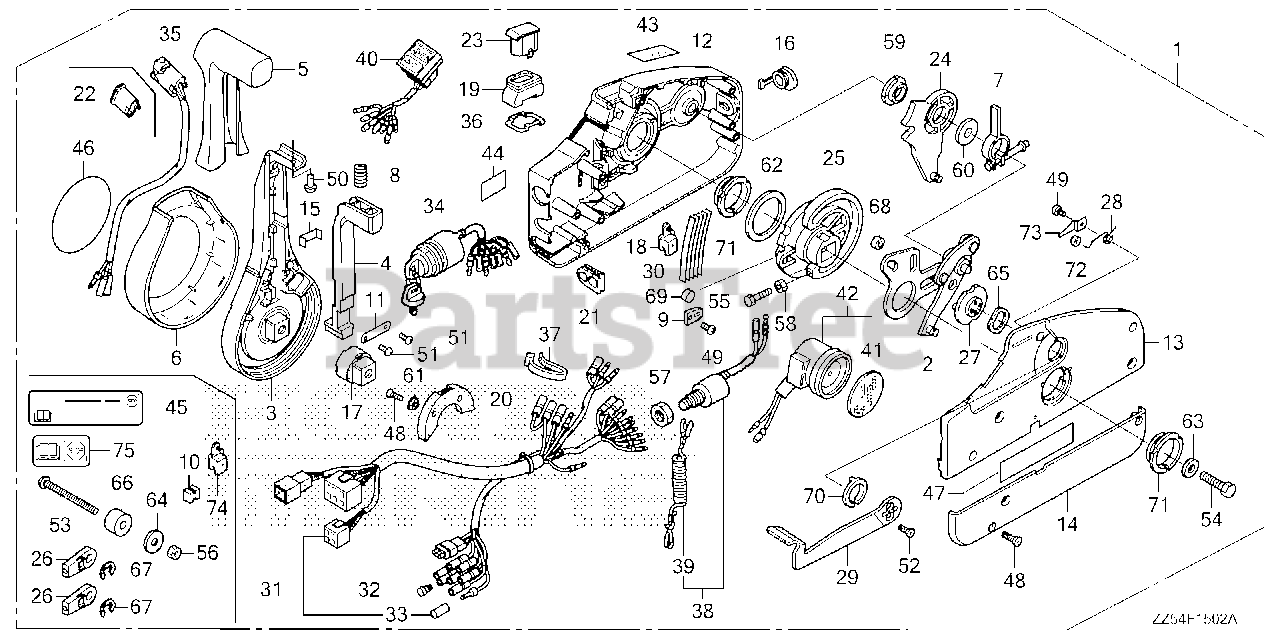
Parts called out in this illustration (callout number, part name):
1	BOX ASSY., REMOTE CONTROL (NHK MEC)
2	PLATE ASSY.
3	LEVER, HAND
4	ARM, NEUTRAL LOCK
5	GRIP
6	COVER, LEVER
7	ARM ASSY., BRAKE
8	SPRING (2)
9	CLIP, DETENT
10	SPACER (1) (LOOSE PARTS)
11	BRACKET
12	HOUSING, FR.
13	HOUSING, RR.
14	PANEL, BACK
16	CAP, RUBBER
17	ADJUSTER
19	SEAL, RUBBER
20	HOLDER, NEUTRAL LOCK
21	GROMMET, WIRE (14)
22	COVER, GRIP
23	CAP, TROLLING CONTROL SWITCH BLANK
24	GEAR ASSY., SHIFT
25	GEAR, DRIVE
26	TERMINAL, CABLE (LOOSE PARTS)
27	DRUM ASSY., FREE THROTTLE
28	SPRING (1)
29	LEVER, FREE THROTTLE
30	SPRING, DETENT
31	CABLE ASSY., REMOTE CONTROL (B)
32	PLUG, CONNECTOR (INNER) (TROLLING CONTROL)
33	PLUG, CONNECTOR (OUTER) (ENGINE NO.)
34	SWITCH ASSY., COMBINATION (SINGLE) (DUAL)
36	PLATE, SWITCH
37	BAND, WIRE
38	SWITCH ASSY., EMERGENCY STOP
39	WIRE, EMERGENCY (SINGLE) (DUAL)
40	LAMP ASSY., INDICATION
41	PLATE, TURN SIGNAL BUZZER DUAL QTY = (2) (SINGLE)
42	BUZZER, WARNING DUAL QTY = (2) (SINGLE)
43	MARK, FAST IDLE
44	MARK, EMERGENCY STOP (US) (LOOSE PARTS)
45	MARK, EMERGENCY STOP (US) (LOOSE PARTS)
46	MARK, EMBLEM
47	LABEL, SIGP
48	SCREW (5X18)
49	SCREW (4X6)
50	SCREW (5X10)
51	SCREW (4X10)
52	SCREW (5X12)
53	SCREW (6X90) (LOOSE PARTS)
54	BOLT (8X50)
55	BOLT (5X25)
56	NUT (6MM) (LOOSE PARTS)
57	NUT, HEX. (16MM) DUAL QTY = (2) (SINGLE)
58	NUT (5MM)
59	BEARING (1)
60	WASHER (3)
61	WASHER (4)
62	WASHER (5)
63	WASHER (8MM)
64	WASHER (7) (LOOSE PARTS)
65	WASHER, WAVE
66	SPACER (2) (LOOSE PARTS)
67	E-RING (6MM) (LOOSE PARTS)
68	ROLLER, DRIVE GEAR CAM
69	ROLLER
70	BEARING (2)
71	BEARING (3)
72	ROLLER, FREE THROTTLE
73	CLIP, ROLLER
